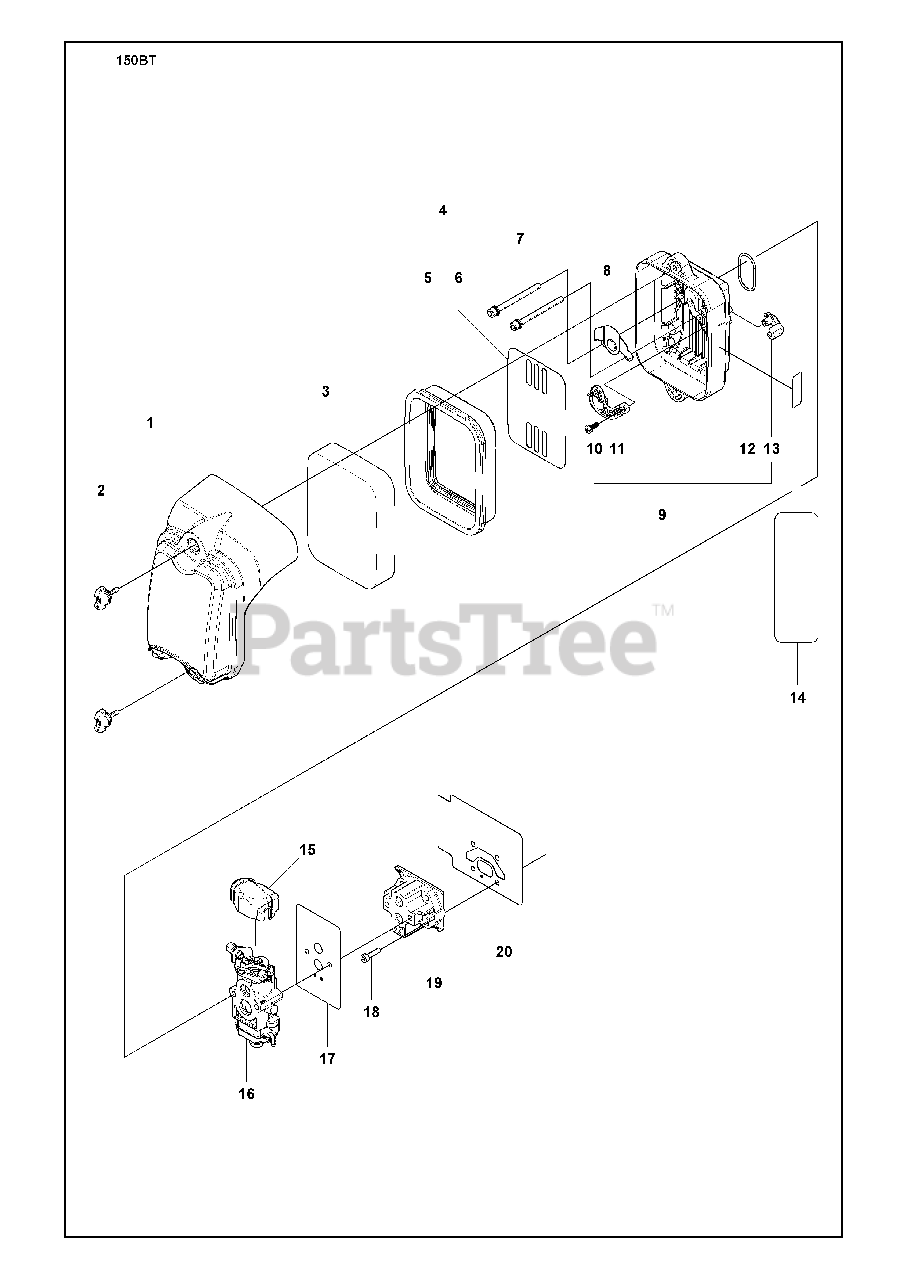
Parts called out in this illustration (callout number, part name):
3	AIR FILTER
9	CARBURETOR BODY
14	RP_LABEL, HOTMARK
15	COVER
16	CARBURETOR
18	BOLT
19	INSULATION
20	RP INSULATOR GASKET
